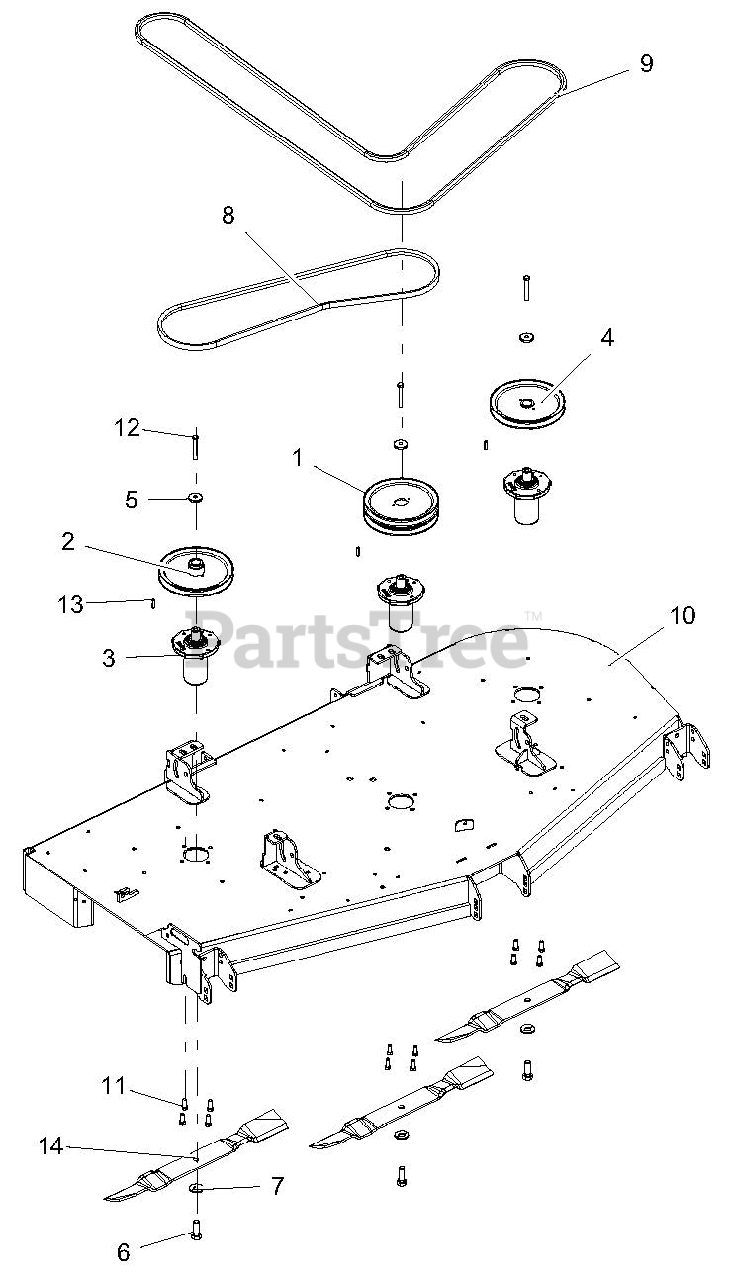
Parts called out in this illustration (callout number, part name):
1	SHEAVE-DOUBLE 1.00"ID X 8.25"OD-BLACK
2	SHEAVE, SINGLE 1.00" ID X 8.25" OD-BLACK
3	SERVICE, ASM SPINDLE- DUCTILE
4	SHEAVE-SINGLE 1.00" X 8.25" OD-BLACK
5	RETAINER, SHEAVE SPINDLE
6	BLT, HEX .62-18X1.75 GR8 YWZC
7	WSHR, BLVL .63X1.625X.14
8	V-BELT, B-COGGED
9	HEX BELT, BB-WRAPED
10	72" SIDE DISCH DECK W/SAFETY DECALS
11	BLT-HEX .38-16X1.00 GR5 YWZC EP30
12	BLT-HEX .38-16X2.75 GR8 YWZC
13	KEY-SQ .250X.250X1.00 RC 40-50
14	BLADE, MOWER -72"
